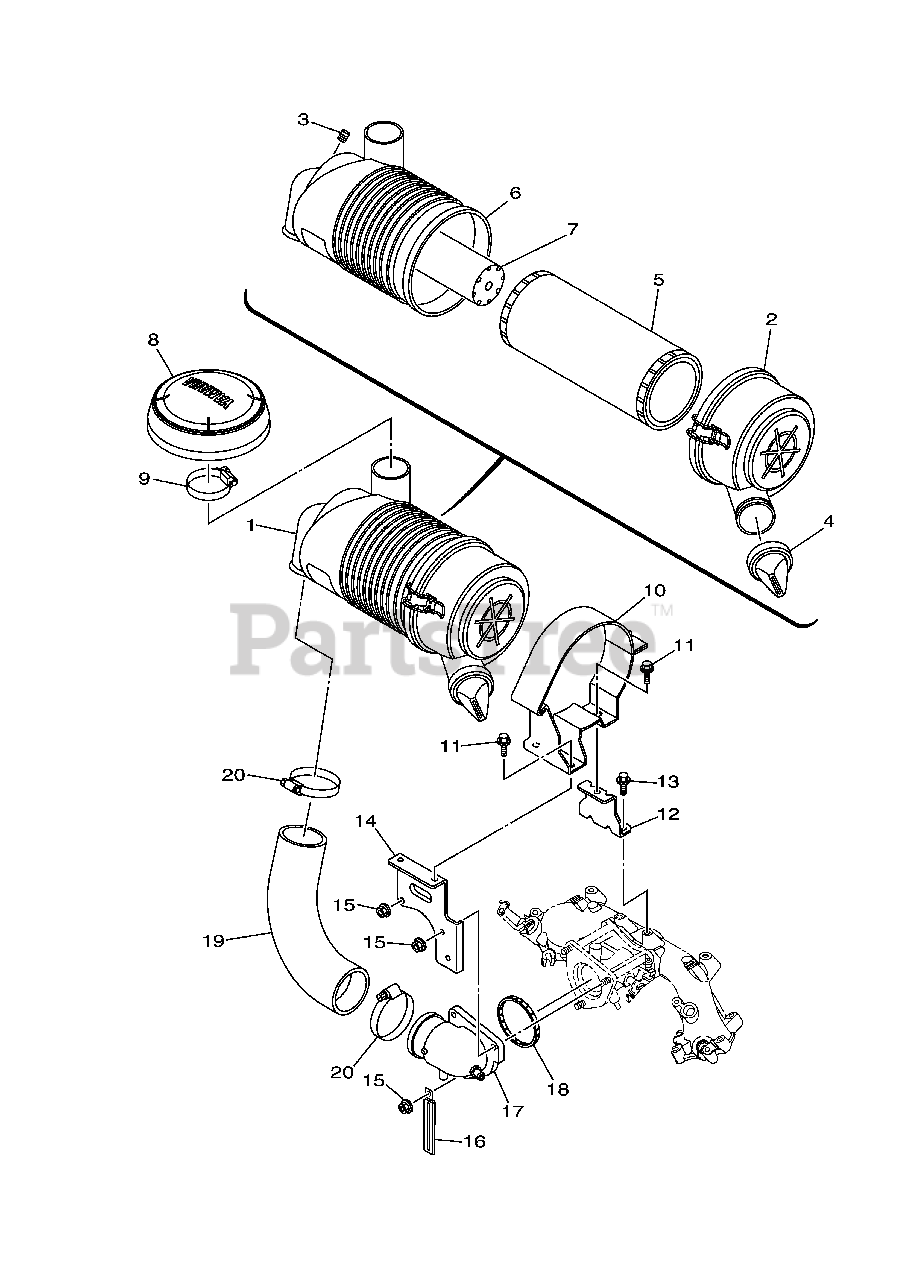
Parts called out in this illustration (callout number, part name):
1	AIR CLEANER ASSY.
2	CAP, CLEANER CASE 1
4	PLUG, BLIND
5	AIR CLEANER, YAMAHA 824
6	CASE, AIR CLEANER 1
7	ELEMENT, AIR CLEANER 2
8	COVER, AIR 1
9	HOSE CLAMP ASSY
11	BOLT, FLANGE
13	BOLT, FLANGE
14	PLATE, STAY
15	NUT, FLANGE
17	JOINT, AIR CLEANER 1
19	JOINT, AIR CLEANER 2
20	HOSE CLAMP ASSY
